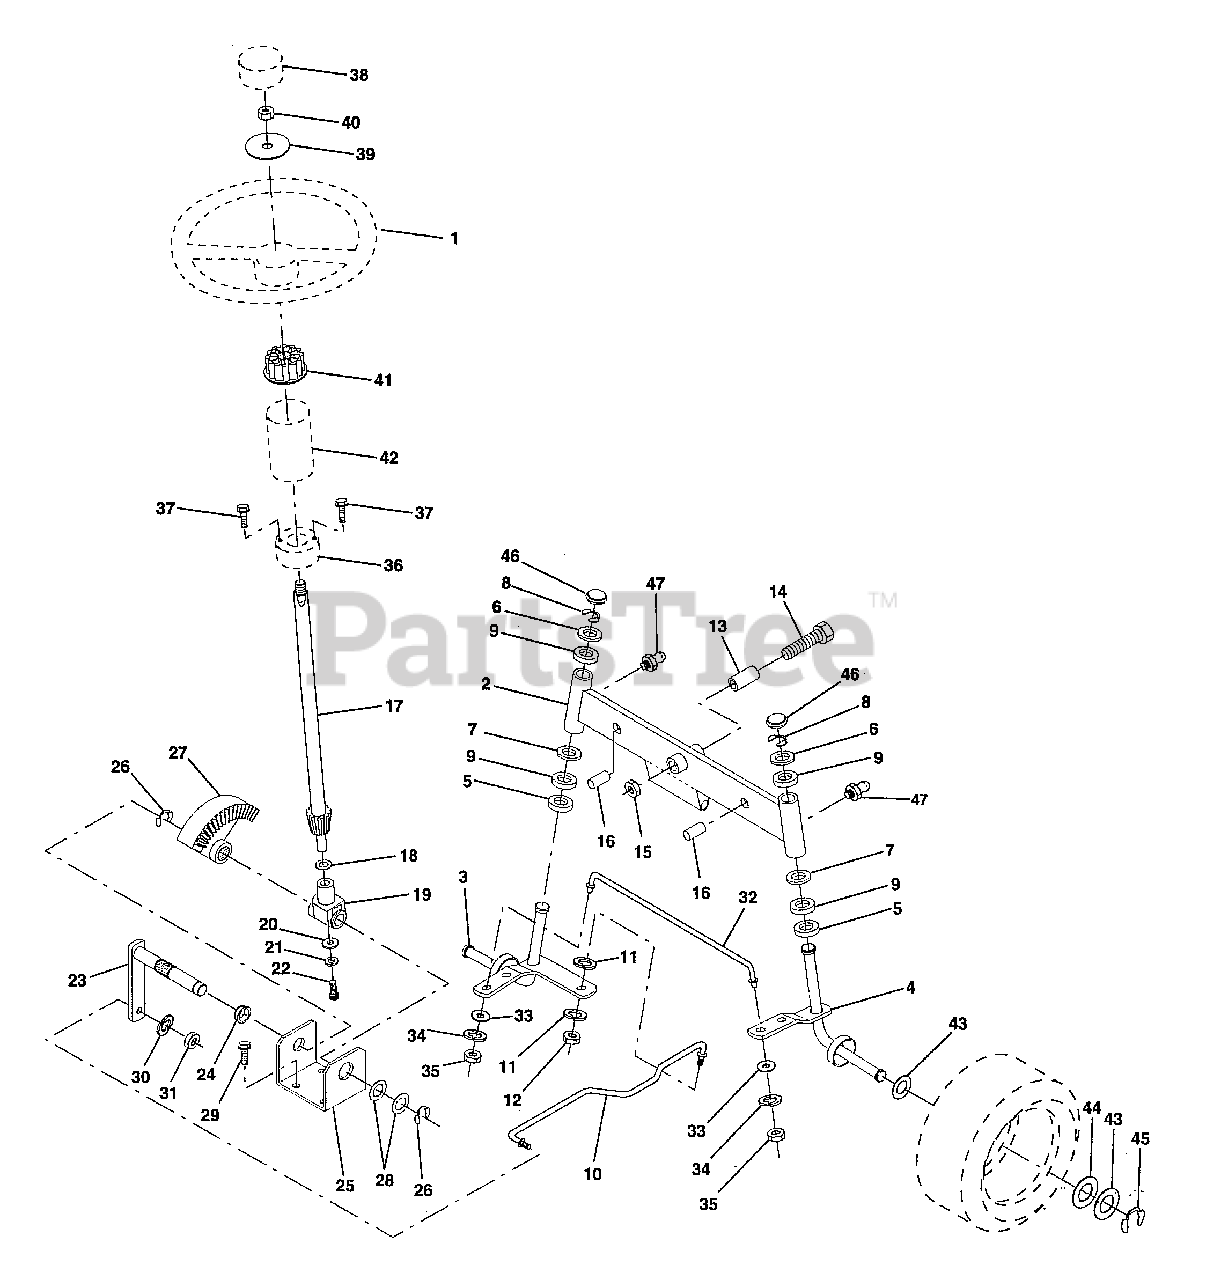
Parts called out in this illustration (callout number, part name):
1	Wheel Steering Auto Grey
2	Axle Asm Fr LT W/gzks 38/42
3	Spindle Asm LH
4	Spindle Asm RH
5	Bearing Race Thrust Harden
6	Washer 25/32 X 1-5/8 X 16 Ga
7	Washer 27/32 X 1-1/4 X 16 Ga
8	Ring Klip #t5304-75
9	Bearing Col Strg Blk
10	Link Drag Sol Ball Jt 20 064
11	Washer Lock Hvy Hlcl Spr 3/8
12	Nut Fin Hex 3/8-24 Unf
13	Spacer Bearing Axle Front
14	Bolt Hex 5/8-11 Unc X 3-1/2
15	Nut Lock Flange 5/8-11 Unc
16	Pin Axle 5/8 X 1 55/1 54 Lg
17	Shaft Asm Strg 20 31 x 3/4 YP YT
18	Washer Thrust 515x 750x 033
19	Support Shaft
20	Washer Shim 1/4 X 5/8 X 062
21	Washer Lock Hvy Helical 1/4
22	Screw Hex Socket 1/4-20 X 5/8
23	Shaft Asm Pittman
24	Nyliner Snap In
25	Bracket Steering
26	Ring Klip #t5304-75
27	Gear Sector
28	Bearing Race Thrust Harden
29	Screw Thdrol 3/8-16x3/4 Ty-tt
30	Washer Lock Hvy Hlcl Spr 3/8
31	Nut Fin Hex 3/8-24 Unf
32	Rod Tie Wire Form 19 75 Elec
33	Washer 11/32 x 3/4 x 16 Ga.
34	Washer, Lock Hvy Hlcl Spr 5/16
35	Locknut 5/16-24 Unf
36	Bushing Strg Blk 742/747 Id
37	Screw Slftp #10-16 X 1/2 Ty-b
38	Insert Cap Strg Wh Aut Hus Gry
39	Washer 53 X 2 25 X 160 Zinc
40	Nut Hex Jam Toplock 1/2-20 Unf
41	Adapter Wheel Strg 758/ 753id
43	Washer 25/32 X 1 1/4 X 16 Ga
44	Washer 25/32 X 1-5/8 X 16 Ga
45	Ring Klip #t5304-75
46	Cap Spindle Fr Top Blk
47	Fitting Grease
